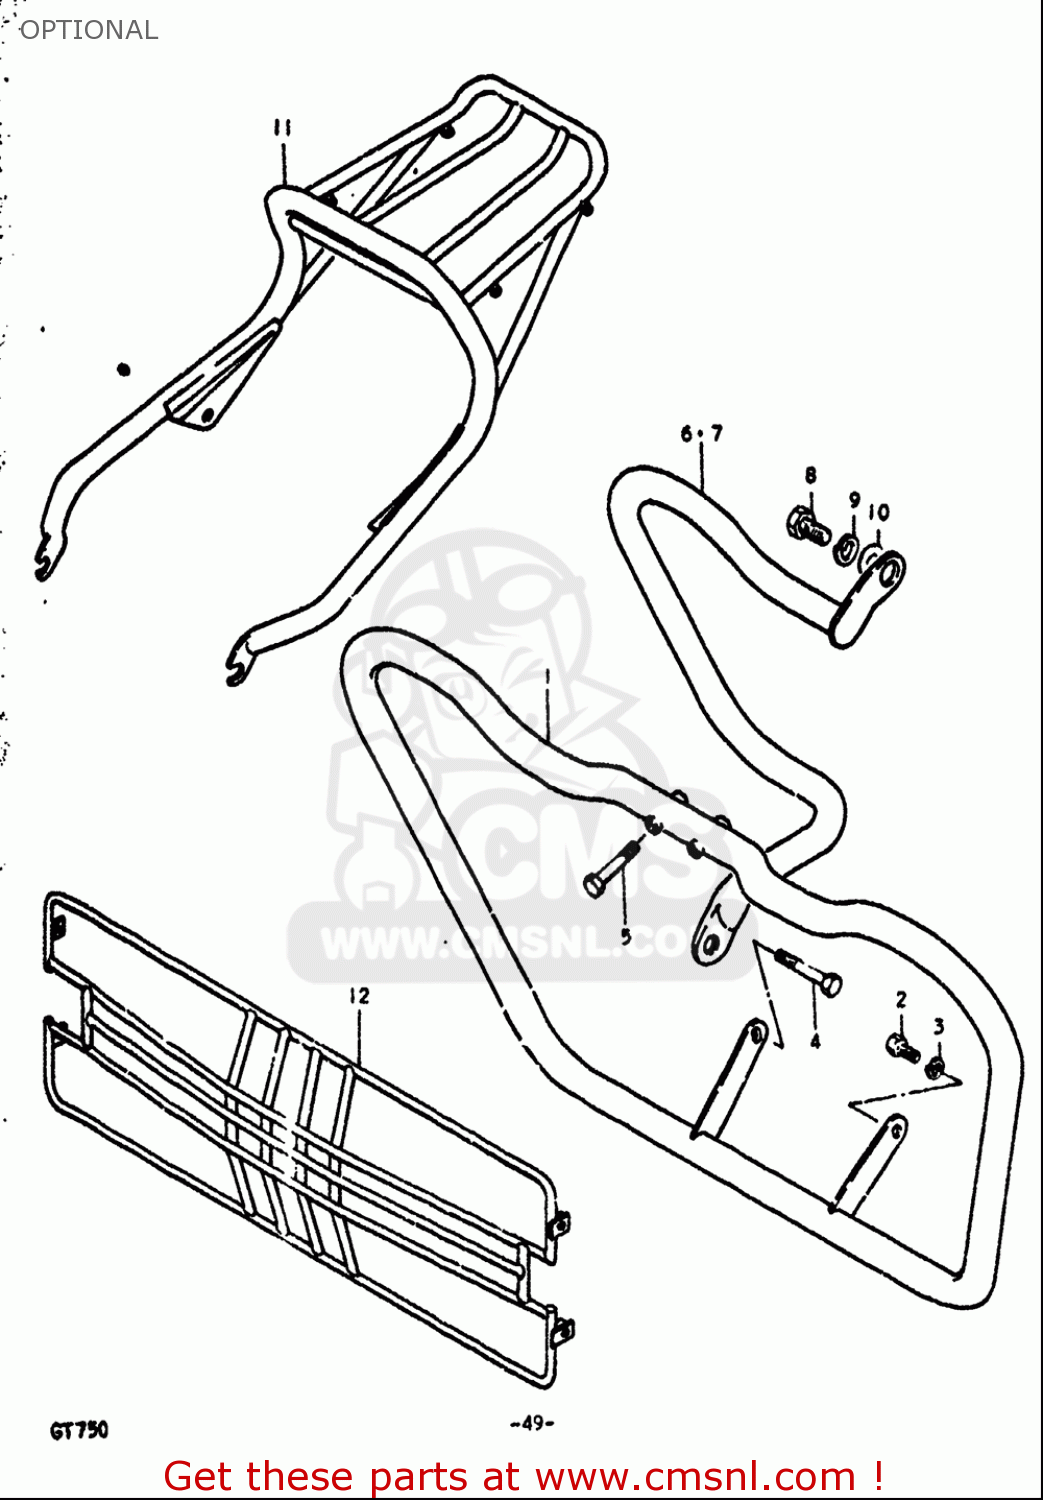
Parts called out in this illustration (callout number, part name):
2	BOLT
3	WASHER,LOCK
4	BOLT
5	BOLT
8	BOLT
9	WASHER,LOCK
10	WASHER
